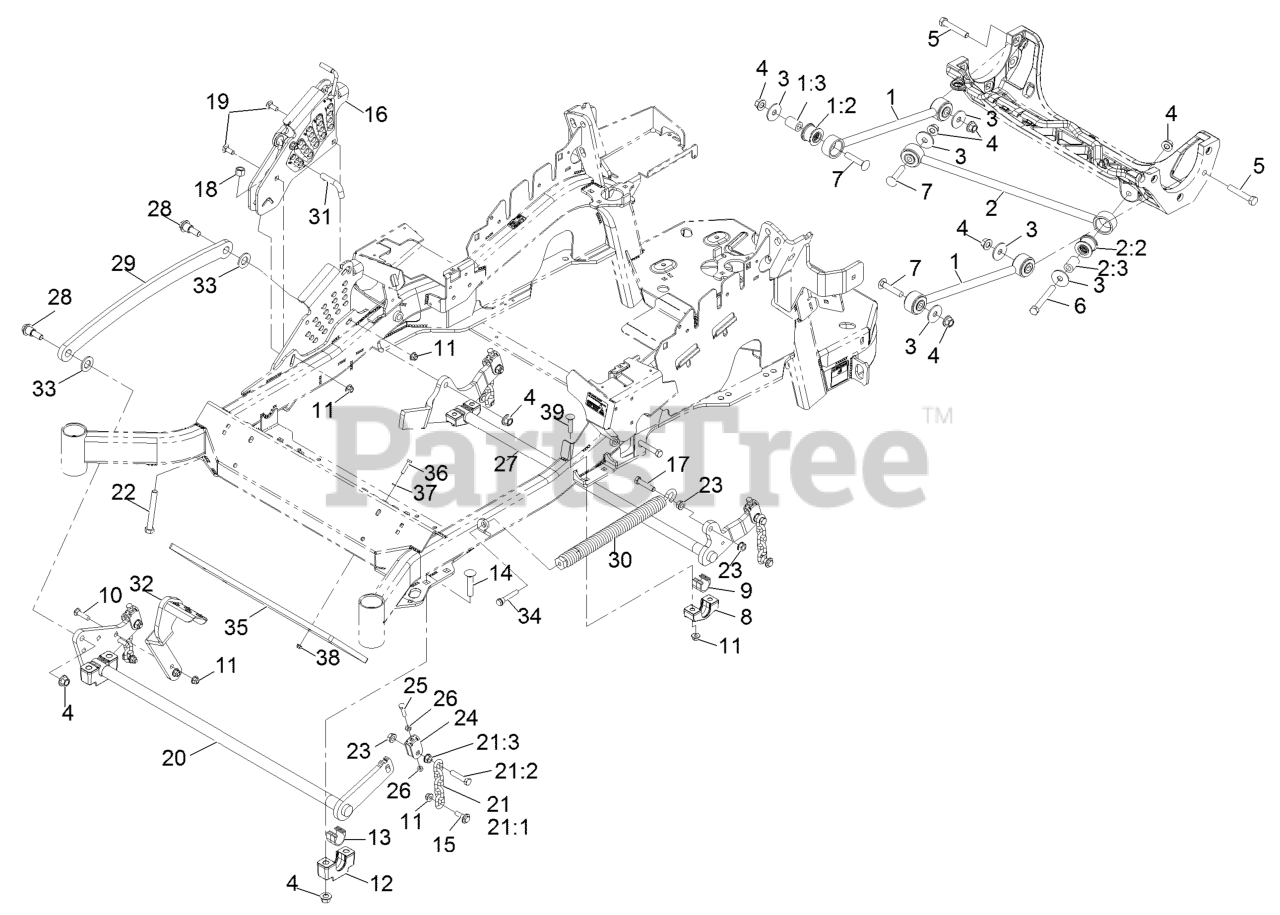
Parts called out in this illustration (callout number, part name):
1	DECK STRUT ASM
1:2	BUSHING-SUSPENSION, RUBBER
2	PANHARD ROD ASM
2:2	BUSHING-SUSPENSION, RUBBER
3	WASHER-THRUST
4	Nut-Lock 1/2-13
5	SCREW-HH
6	SCREW-HH
7	SCREW-CARR
9	BEARING-CROSS SHAFT, REAR
10	SCREW-CARR
11	NUT-HF, NI
12	SUPPORT-CROSS SHAFT, BEARING
13	BEARING-CROSS SHAFT, FRON
14	Bolt-Carriage 1/2-13 X 2 1/2 Spl Neck
15	SCREW-SHOULDER, HHF
16	HOC ASM
17	SCREW-HH
18	NUT-LOCK, NI
19	BOLT-CARR
21	DECK LIFT CHAIN ASM
21:1	CHAIN-LIFT, DECK
21:2	SCREW-HH
22	BOLT-TAP
24	YOKE-ADJUST, DECK
25	SCREW-HH
26	NUT-JAM
27	LIFT-DECK, REAR
28	SCREW-SHOULDER, HHF 1/2-13 X 1.12
29	LINK-LIFT, DECK
30	SPRING-EXTENSION
31	PIN-HOC
32	LEVER-FOOT
33	WASHER-FLAT
34	BOLT-SHOULDER
35	WEIGHT,TOE BOARD
36	SCREW-HH
37	WASHER-FLAT
39	SCREW-CARR
